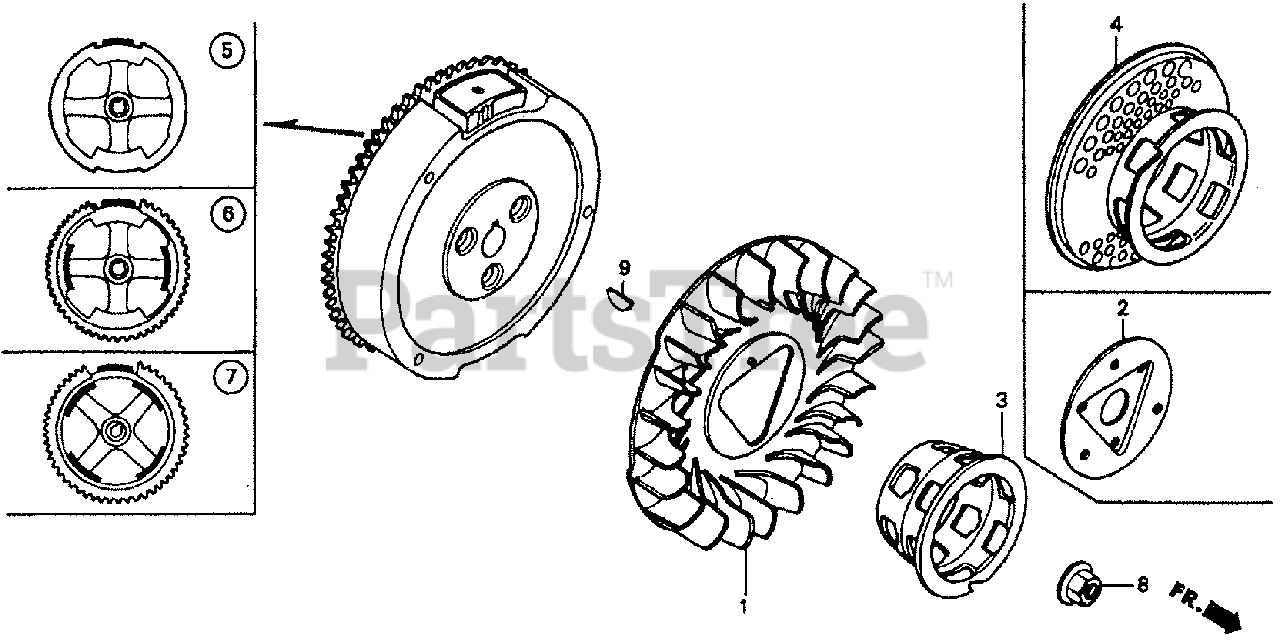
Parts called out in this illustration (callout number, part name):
1	FAN, COOLING
2	PLATE, COOLING FAN SETTING
5	FLYWHEEL
8	NUT, SPECIAL (16MM)
9	KEY, SPECIAL WOODRUFF (25X18)
